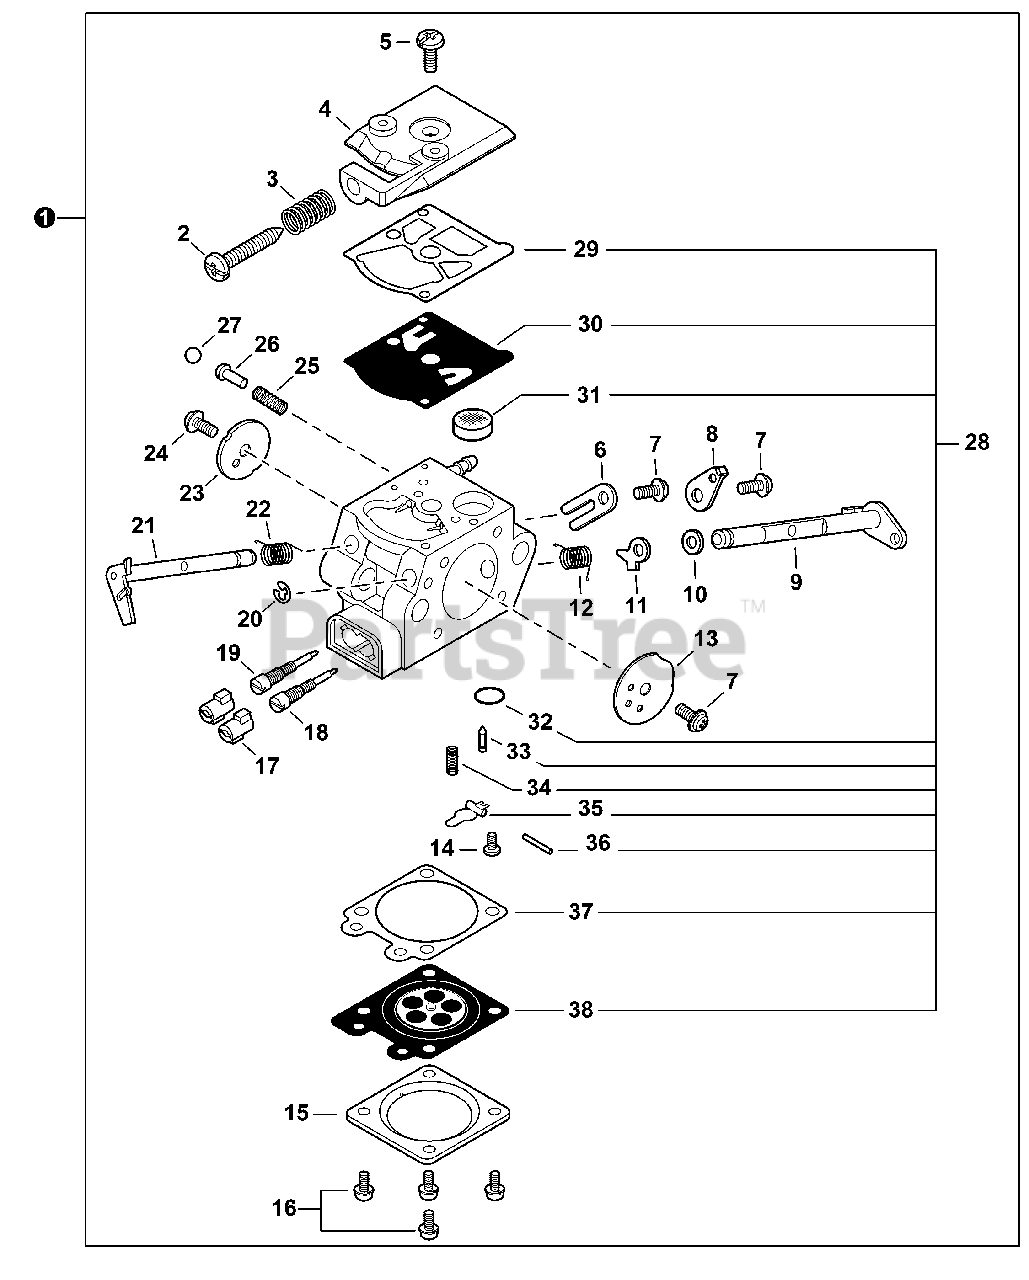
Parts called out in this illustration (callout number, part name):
1	CARBURETOR - WT-946
2	SCREW, IDLE ADJUST
3	SPRING, IDLE ADJUST
4	COVER, PUMP
6	CLIP, THROTTLE SHAFT
8	LEVER, THROTTLE
9	SHAFT, CHOKE
11	LEVER, FAST IDLE
13	VALVE, CHOKE
14	SCREW, METERING LEVER PIN
15	COVER, METERING DIAPHRAGM
17	CAP, LIMITER
18	NEEDLE, HIGH MIXTURE
19	NEEDLE, LOW MIXTURE
21	SHAFT ASSY, THROTTLE
22	SPRING, THROTTLE RETURN
23	VALVE, THROTTLE
25	SPRING, START VALVE
26	PISTON ASSY
28	REPAIR KIT, CARBURETOR
29	GASKET, PUMP
30	DIAPHRAGM, PUMP
31	SCREEN, INLET
32	PLUG, WELCH
33	VALVE, INLET NEEDLE
34	SPRING, METERING LEVER
35	LEVER, METERING
36	PIN, METERING LEVER
37	GASKET, METERING DIAPHRAGM
38	DIAPHRAGM, METERING
